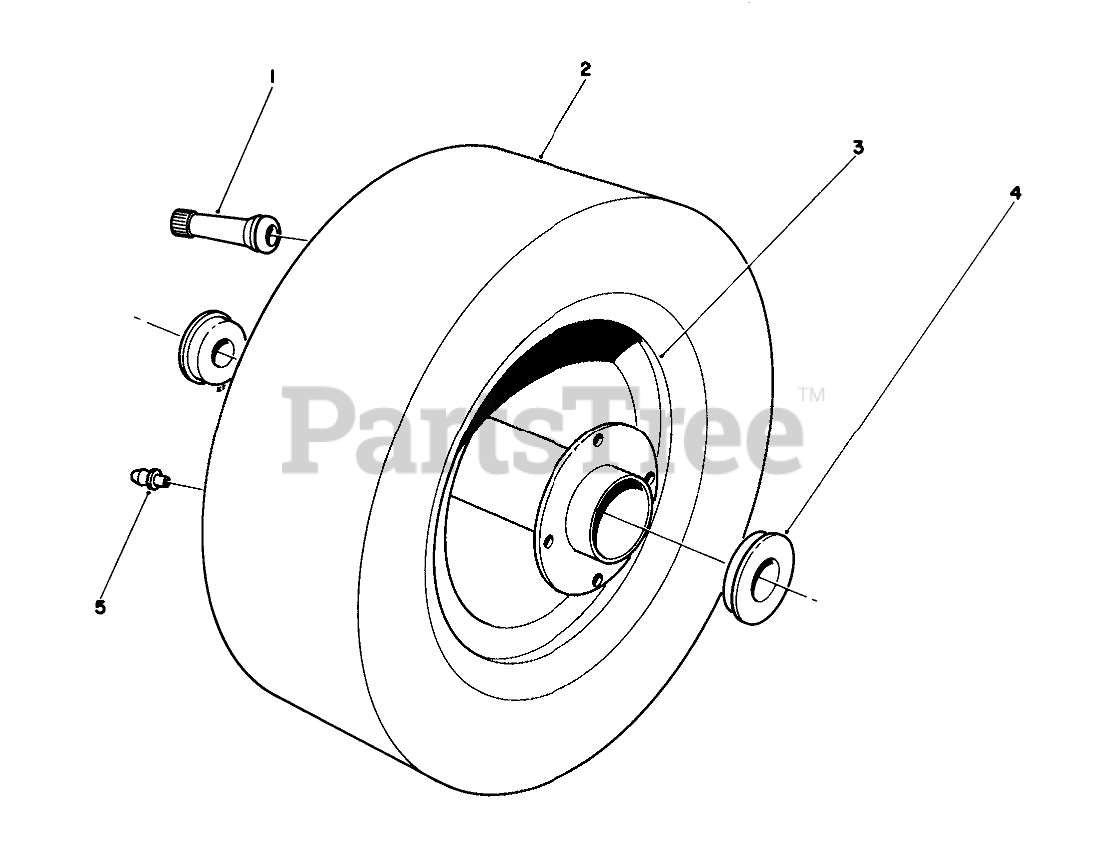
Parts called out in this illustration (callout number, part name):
1	STEM-VALVE
2	Tire
3	REAR RIM
4	BEARING-BALL, FLANGED
5	FITTING-GREASE
